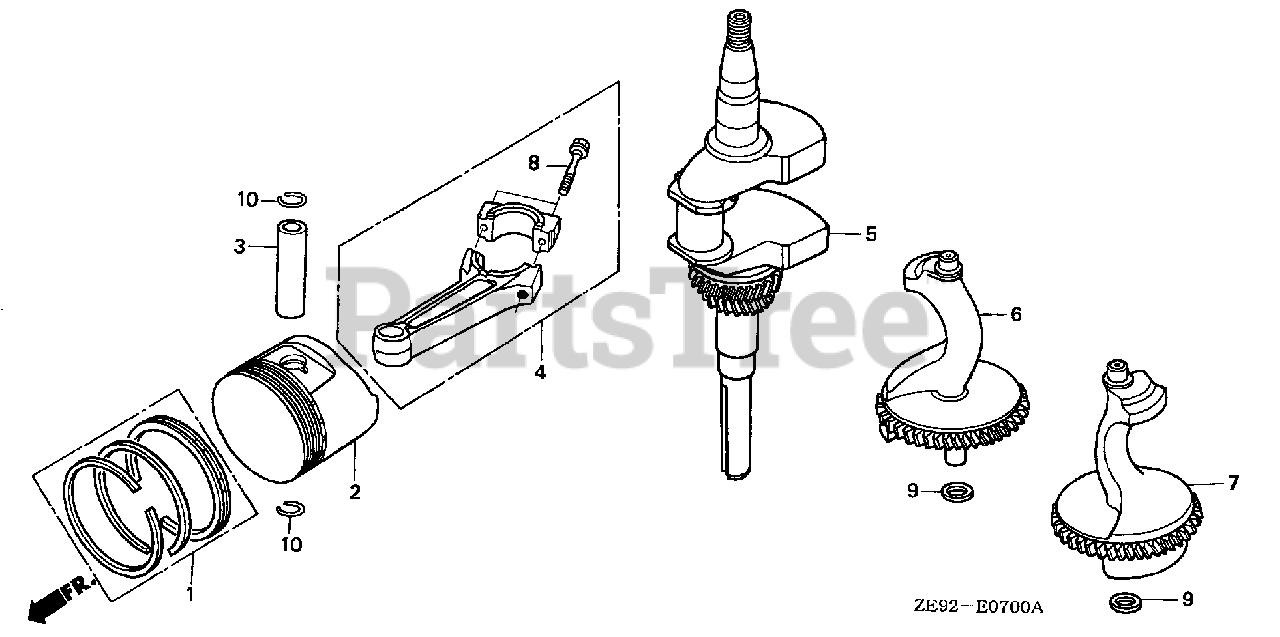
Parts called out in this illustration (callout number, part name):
1	RING SET, PISTON (STD) (NIPPON)
1	RING SET, PISTON (0.25)
1	RING SET, PISTON (0.50)
1	RING SET, PISTON (0.75)
2	PISTON (STD)
2	PISTON (0.25)
2	PISTON (0.50)
2	PISTON (0.75)
3	PIN, PISTON
4	ROD ASSY., CONNECTING
5	CRANKSHAFT
6	WEIGHT A, BALANCER
7	WEIGHT B, BALANCER
8	BOLT, CONNECTING ROD
9	WASHER, THRUST (15MM)
10	CLIP, PISTON PIN (20MM)
